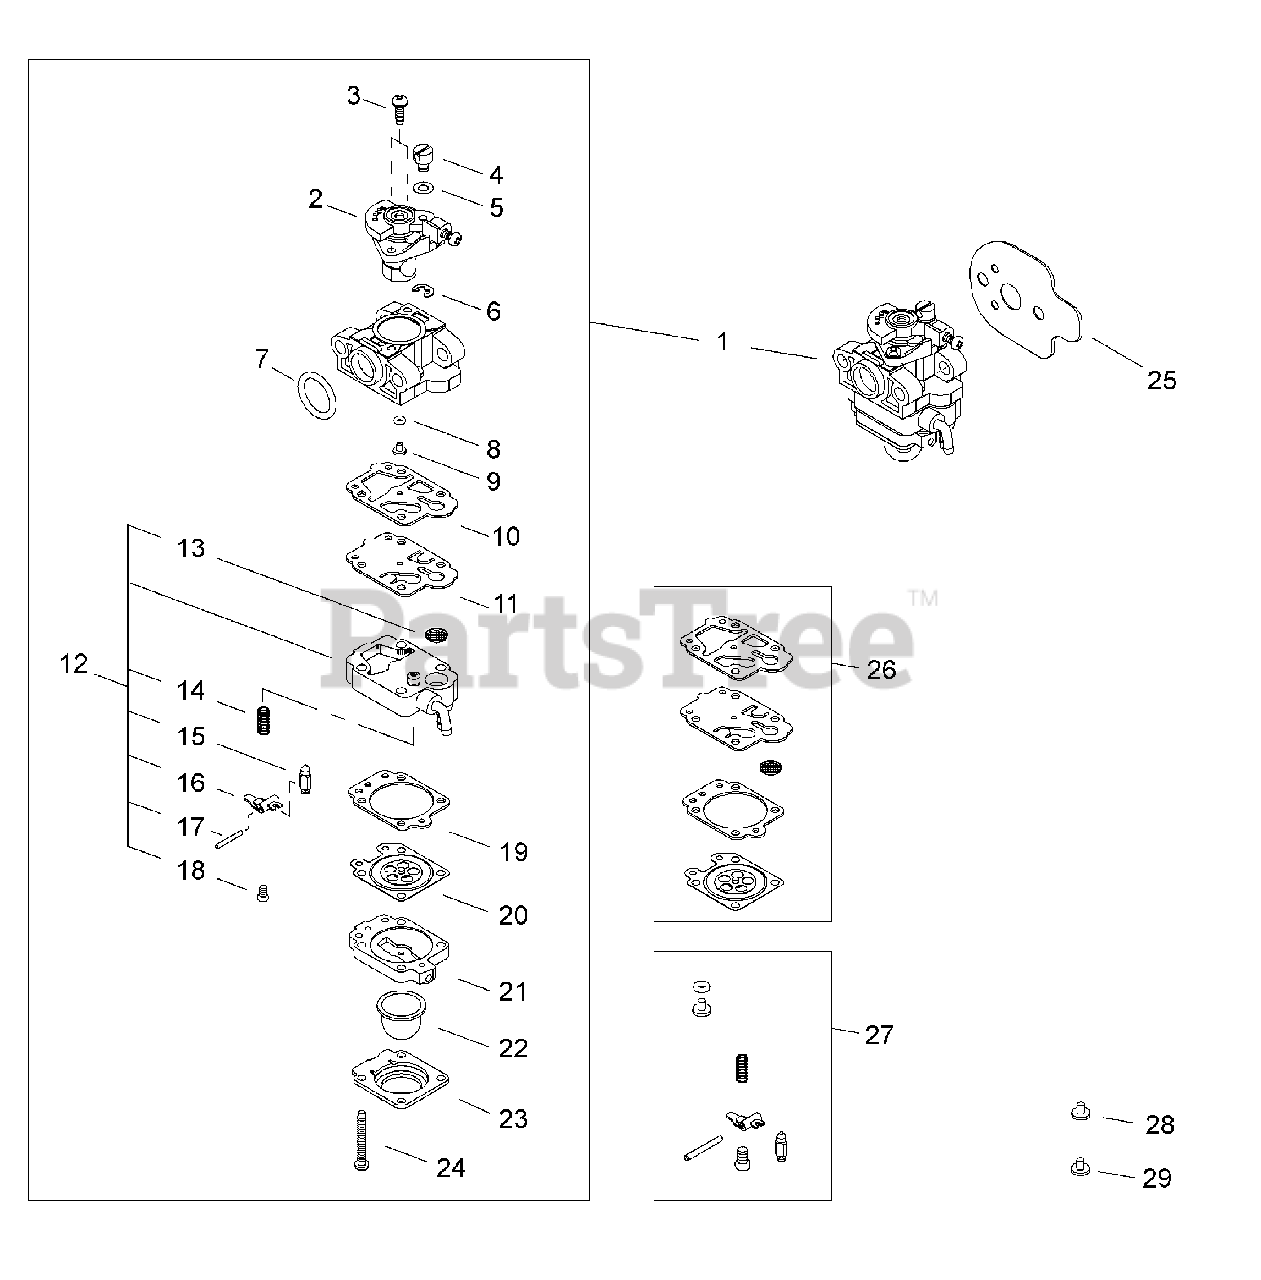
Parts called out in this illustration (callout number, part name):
1	CARBURETOR
2	THROTTLE VALVE ASSY
3	SCREW
4	SWIVEL
5	WASHER
6	RING, RETAINING
7	O-RING - 15
8	O-RING
9	JET, MAIN
10	GASKET, PUMP
11	DIAPHRAGM, PUMP
12	PUMP BODY ASSY
13	STRAINER
14	SPRING, METERING LEVER
15	VALVE, INLET NEEDLE
16	LEVER, METERING
17	PIN, METERING LEVER
18	SCREW, METERING LEVER PIN
19	GASKET, METERING
20	DIAPHRAGM, METERING
21	BASE, PURGE
22	BULB, PURGE
23	RETAINER, PURGE BULB
24	SCREW, PUMP COVER
25	GASKET, INTAKE
26	DIAPHRAGM/GASKET KIT
27	INLET NEEDLE VALVE KIT
28	JET, MAIN - 1000M #40
29	MAIN JET - 2000M #39
